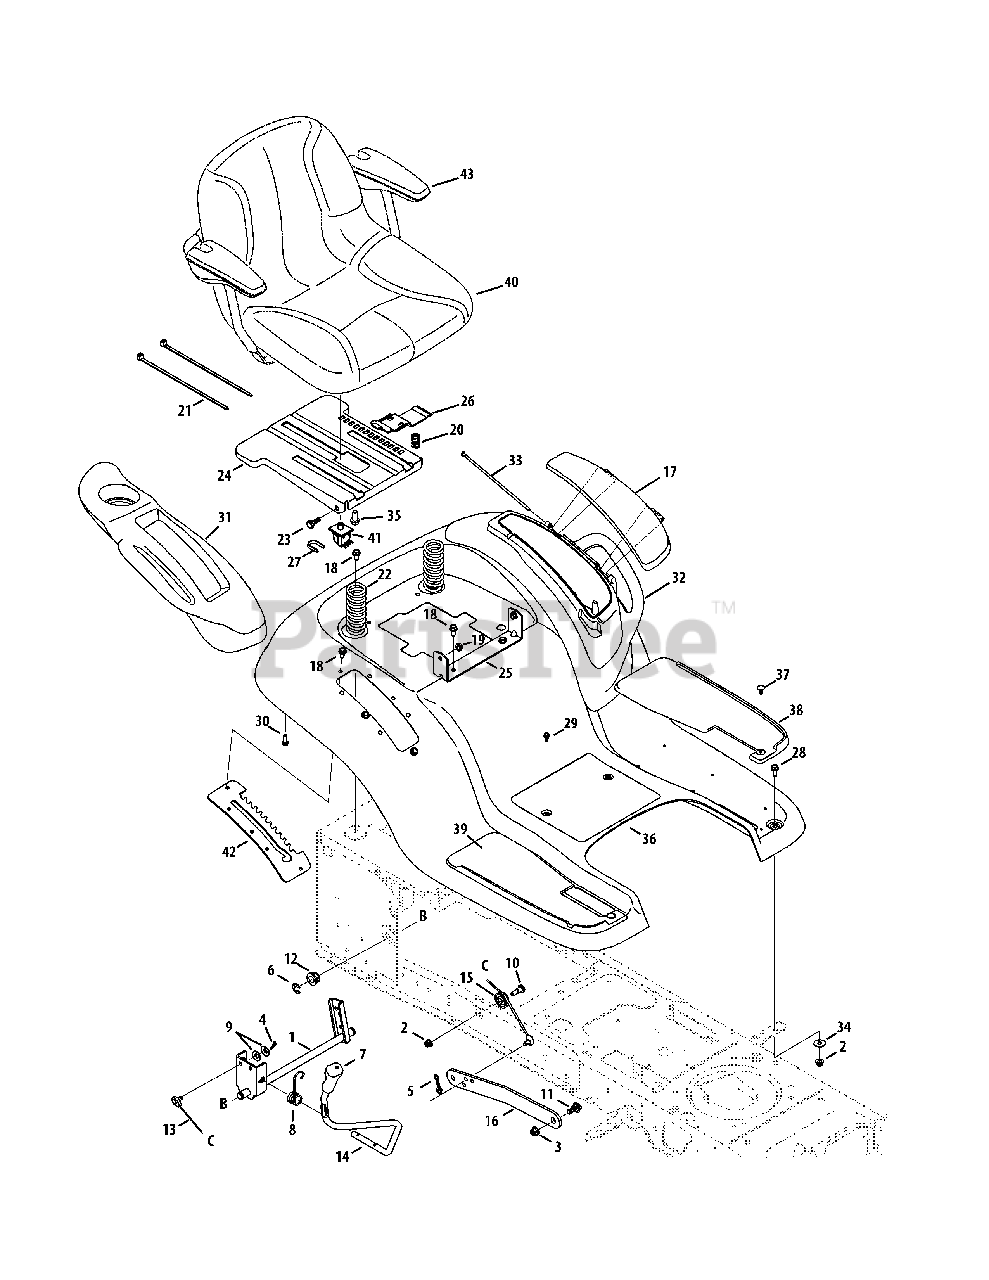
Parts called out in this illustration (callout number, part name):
1	Shaft Ass’y, Lift, 54"
2	Nut, Flange Lock, 5/16-18, Grf
3	Nut, Flange Lock, 3/8-16, Grf
4	Pin, Cotter, .072 Dia. x 1.13
5	Pin, Cotter, Bow-Tie 72
6	Ring, E Type, .625 Dia. Shaft
7	Grip, Handle, Cub, .50 ID
8	Spring, Torsion
9	Washer, Spring, .401 x .870 x .063
10	Screw, Shoulder, .437 x .470, 5/16-18
11	Bolt, Shoulder, .50, 3/8-16
12	Bearing, Hex Flange
13	Cable, Lift, 16.16
14	Handle, Lift,
15	Pulley, Roller, Cable
17	Door, Cover, Fender
18	Screw, Self-tapping, 5/16-18, .750,
19	Nut, Flange Lock, 5/16-18, Gr5, Sd Lk
20	Spring, Compr’, .68 x 1.065 x .055
21	Cable, Tie, 3/16 x .05 x 7.4
22	Spring, Comprs, 1.50 x 3.90 x .200
23	Screw, Shoulder, .437 x .268, 5/16-18
24	Bracket, Mounting, Seat
25	Bracket, Pivot, Seat
26	Lever, Seat Adjustment
27	Clip, Retaining, Switch
28	Hex Screw, 5/16-18, .75, Gr5, Std
29	Screw, Self-tapping, 1/4-20, 0.500,
30	Screw, HL, 1/4-15, 0.750,
31	Cover, Fender, RH
32	Cover, Fender, LH
34	Washer, Flat .344 x 1.00 x .063
35	Hex Flange Screw, 3/8/16, .875, Gr5
36	Fender, Cub Hydro
37	Clip, Ratchet, .250 Dia
38	Pad, Foot, LH
39	Pad, Foot, RH
40	Seat, High Back Cloth w/o Arm Rest
41	Switch, Seat
42	Bracket, Lift
43	Arm Rest Kit
